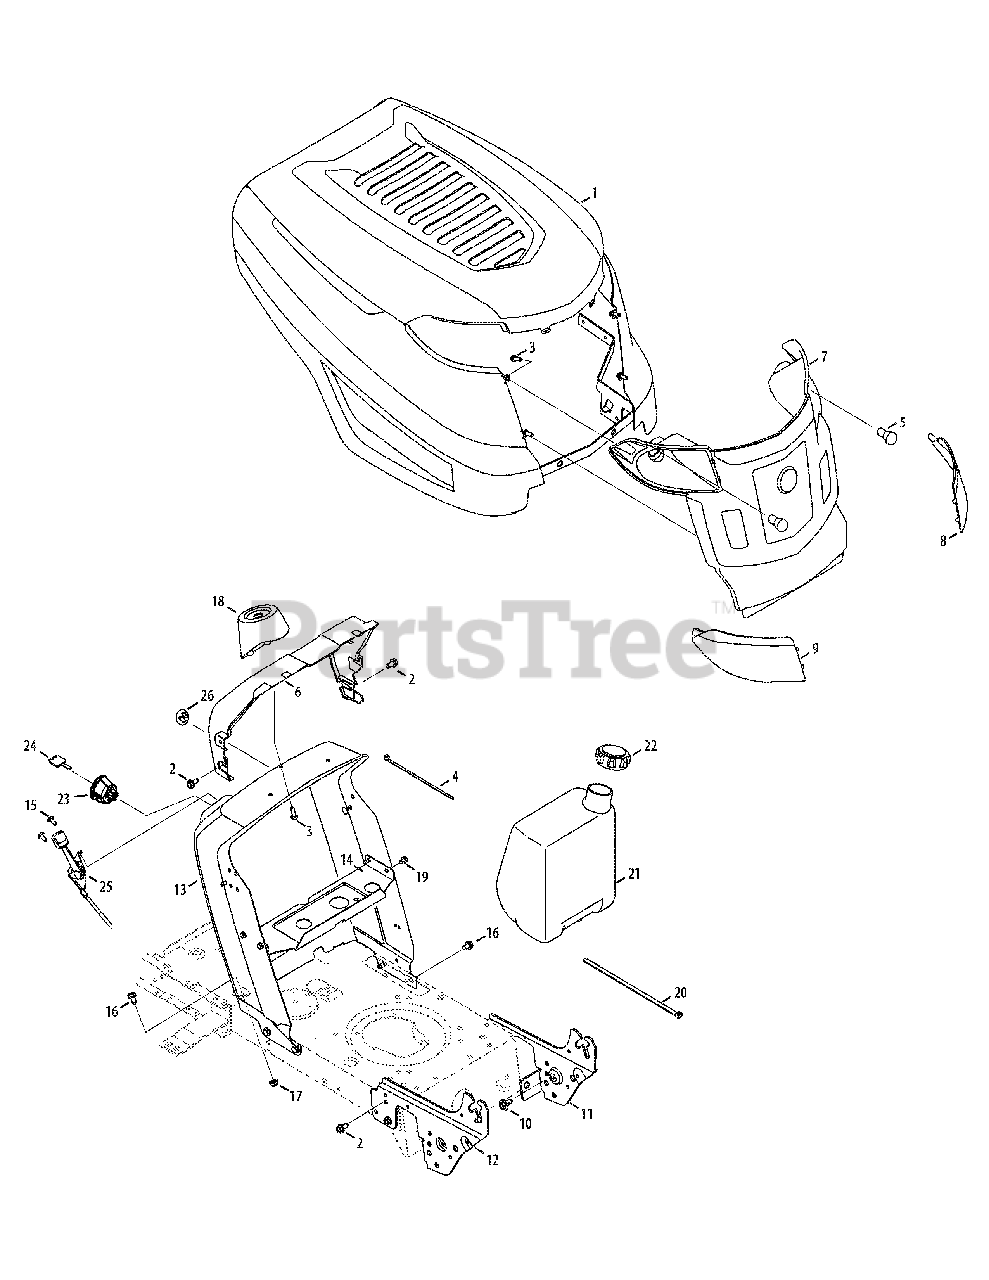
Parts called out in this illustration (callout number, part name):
2	Screw, 5/16-18, 0.750
3	Screw, 1/4-15, .750
4	Cable Tie, 3/16 x .05 x 7.4
5	Headlamp, 12V
6	Dash Collar
7	K-Style Grill
10	Screw, Shldr, .43 x .29, 5/16-18
15	Screw, 1/4-14, .500
16	Screw, 5/16-18, 0.625
17	Flange Lock Nut 5/16-18
18	Support, Steering
19	Screw, 1/4-20, 0.500
20	Cable Tie, 34.75
21	Fuel Tank, 1.5 gal.
22	Fuel Tank Cap
23	Igntion, Switch (No RMC) 3 Position
24	Key
25	Throttle/Choke Control, 25.0
26	Choke Plug
